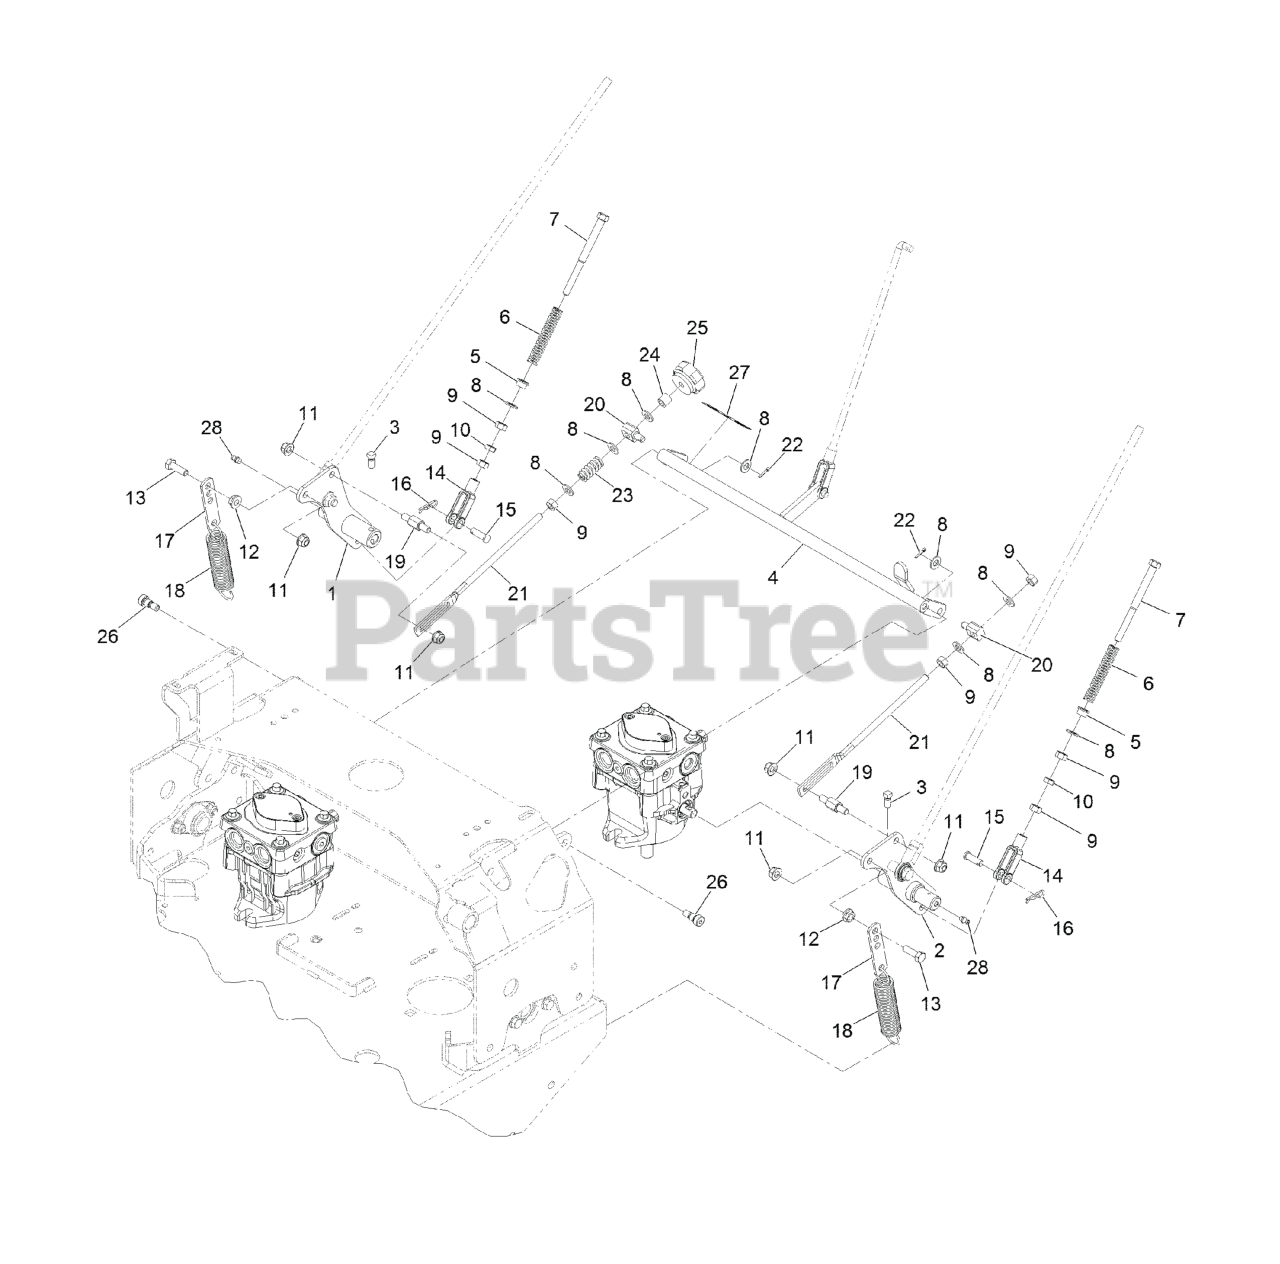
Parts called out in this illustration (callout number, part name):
1	WELD, MOTION CONTROL, RT
2	WELD, MOTION CONTROL, LT
3	SCREW-SET
4	WELD, SPEED CONTROL
5	BUSHING-FLANGED
6	SPRING,COMPRESSION (NEUT)
7	BOLT-RETURN, NEUTRAL
8	WASHER-PLAIN
9	NUT-HEX
10	NUT-JAM
11	NUT-HF, NI
13	SCREW-HH
14	YOKE-ADJUSTABLE
15	PIN-CLEVIS
16	PIN-COTTER
17	TAB-SPRING, EXTENSION
18	SPRING-EXTENSION
19	PIN, MOTION CONTROL
20	SWIVEL-ADJUSTABLE, SHORT
21	LINK-CONTROL, SPEED
22	PIN-COTTER
23	SPRING-COMPRESSION
25	KNOB-TRACKING
26	SCREW-HSH
27	DECAL-TRACKING ADJUSTMENT
28	FITTING-GREASE
